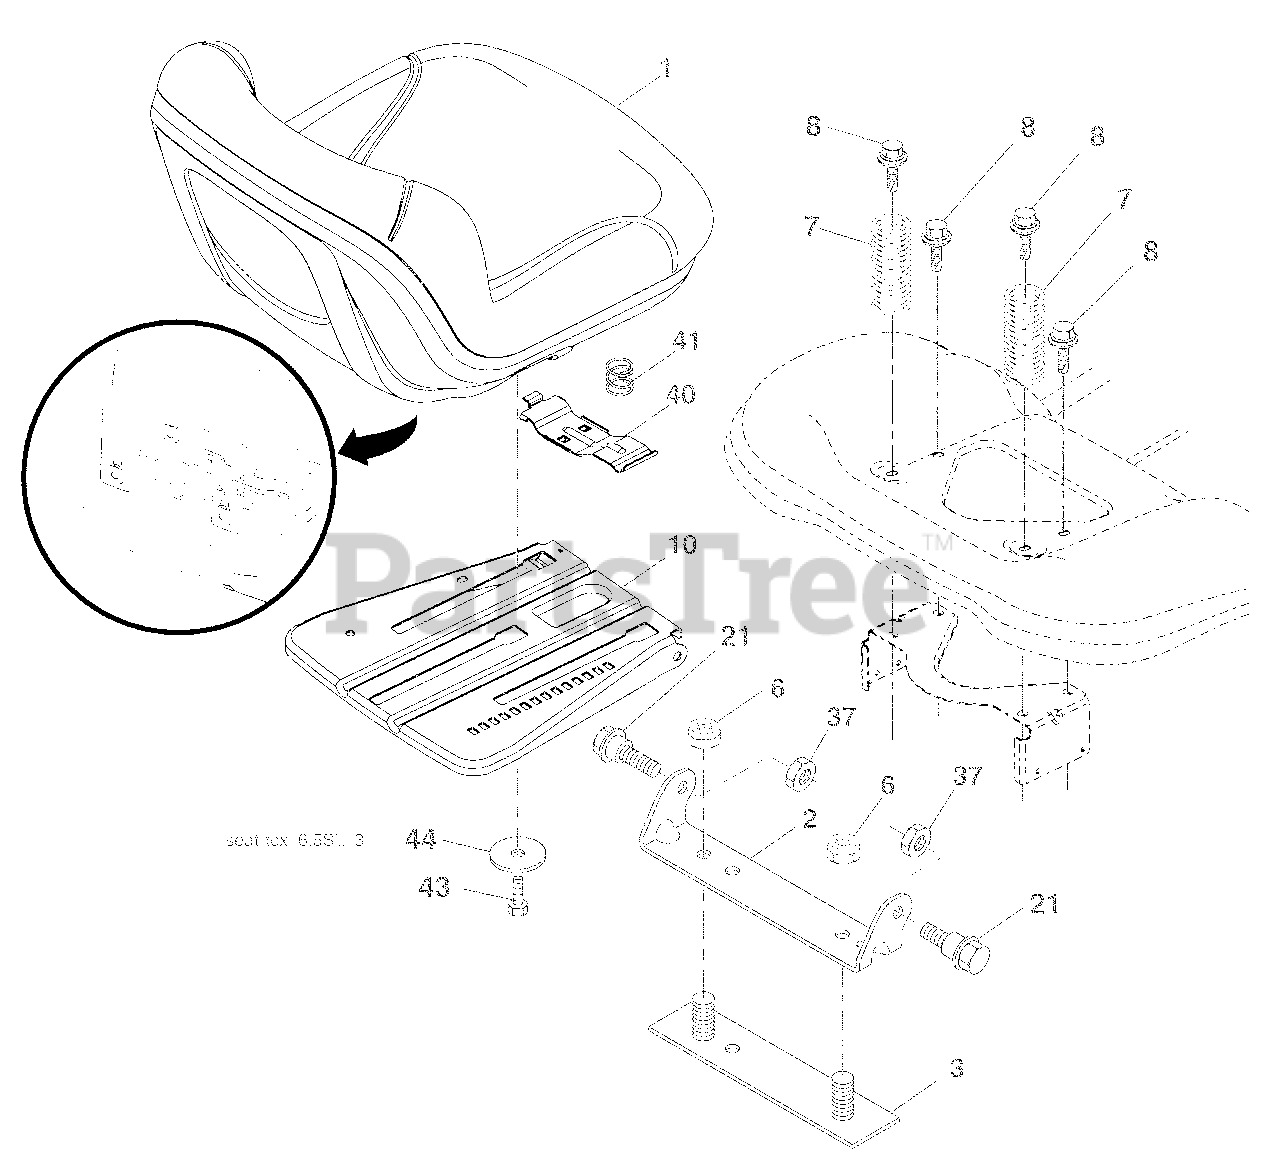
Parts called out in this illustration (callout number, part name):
1	Seat
2	Bracket Pivot Fender
3	Strap, Asm Fender
6	Nut, Lock w/Ins. 3/8-16 unc
7	Spring, Seat Cprsn
8	Bolt 5/16-18 unc x 3/4 w/Sems
10	Pan, Seat
21	Bolt, Shoulder 5/16-18
37	Nut, Lock 5/16-18 unc
40	Handle Slide Seat
41	Spring Latch Seat
43	Bolt Fin Hex 3/8-16 unc x 3/4
44	Washer 13/32 x 2-3/8 x 12 Ga.
